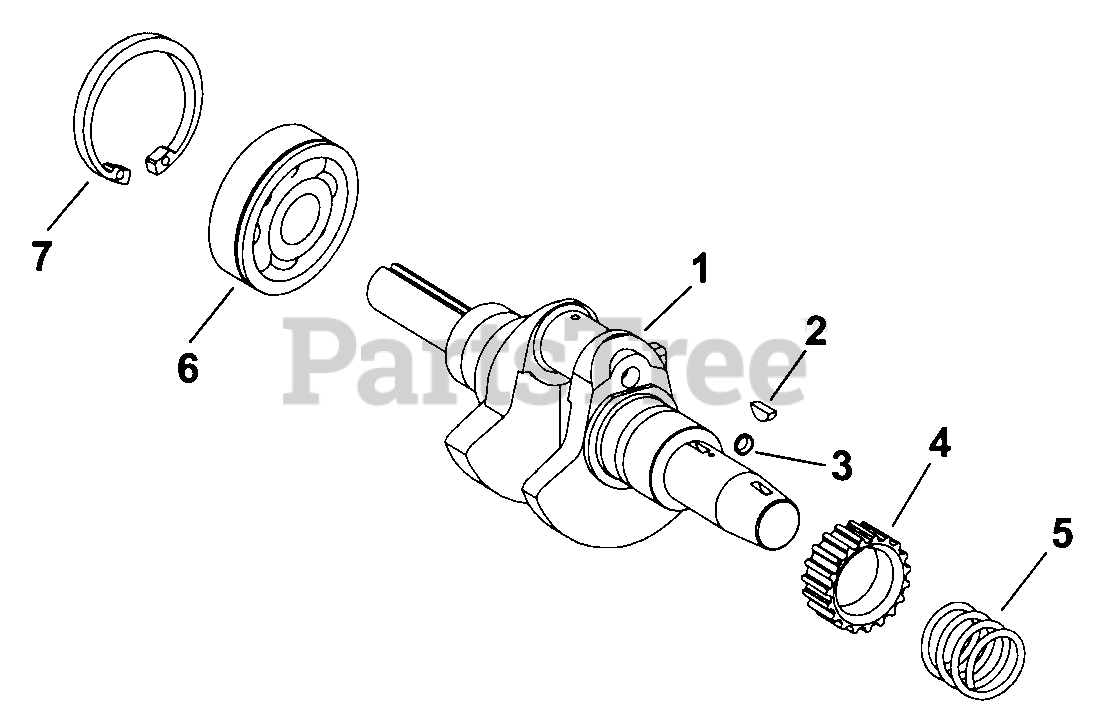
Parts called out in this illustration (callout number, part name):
1	CRANKSHAFT - DISCONTINUED
2	KEY, 3/16" X 5/8"
3	PLUG, CUP
5	SPRING, SPACER
6	BEARING, BALL
7	RING, RETAINING - DISCONTINUED
